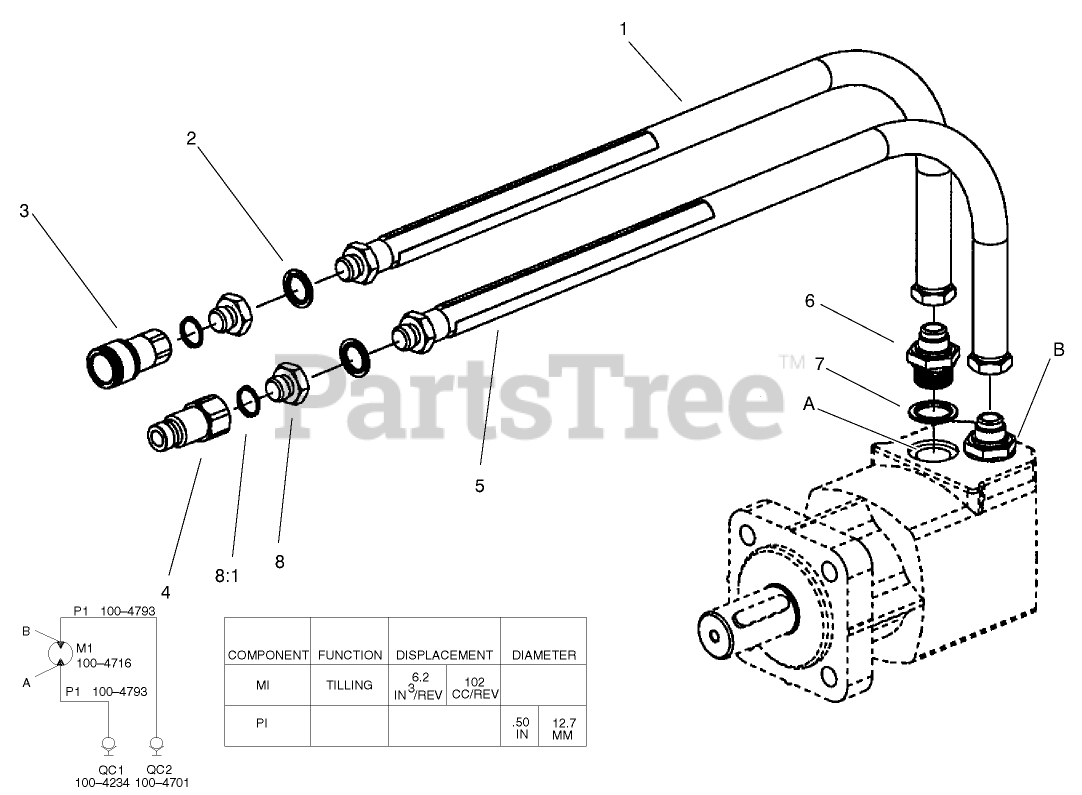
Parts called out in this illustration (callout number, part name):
1	HYDRAULIC HOSE ASM
2	GASKET
3	COUPLER-FACE, FLUSH
4	NIPPLE-CONNECT, PRESSURE
5	SHEATH-PROTECTION, HOSE
6	ADAPTER-HYD
7	GASKET
8	ADAPTER-HYD
8:1	O-RING
